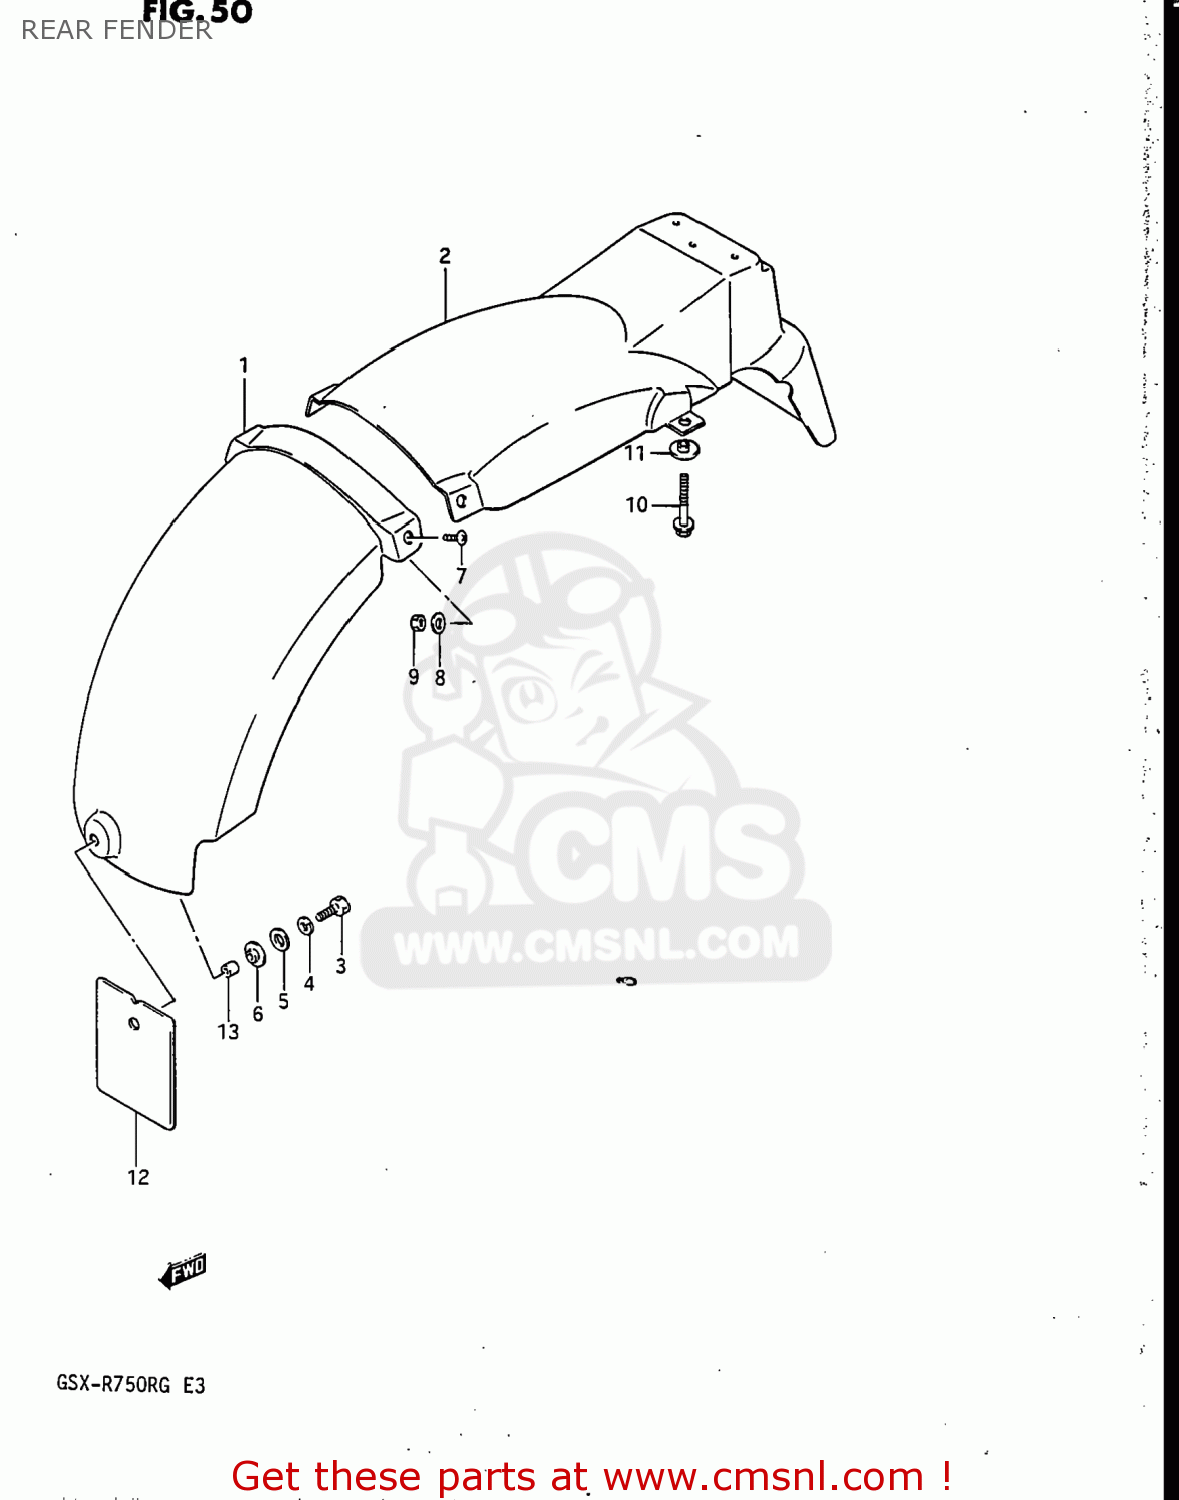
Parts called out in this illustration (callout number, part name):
1	FENDER,REAR
2	FENDER,REAR
3	BOLT 6X30
4	WASHER,LOCK
5	WASHER
6	WASHER
7	SCREW
8	WASHER
9	NUT 6MM
10	BOLT
11	WASHER
12	MUD GUARD,REAR FENDER,FRONT
13	SPACER (6.8X10X10)
